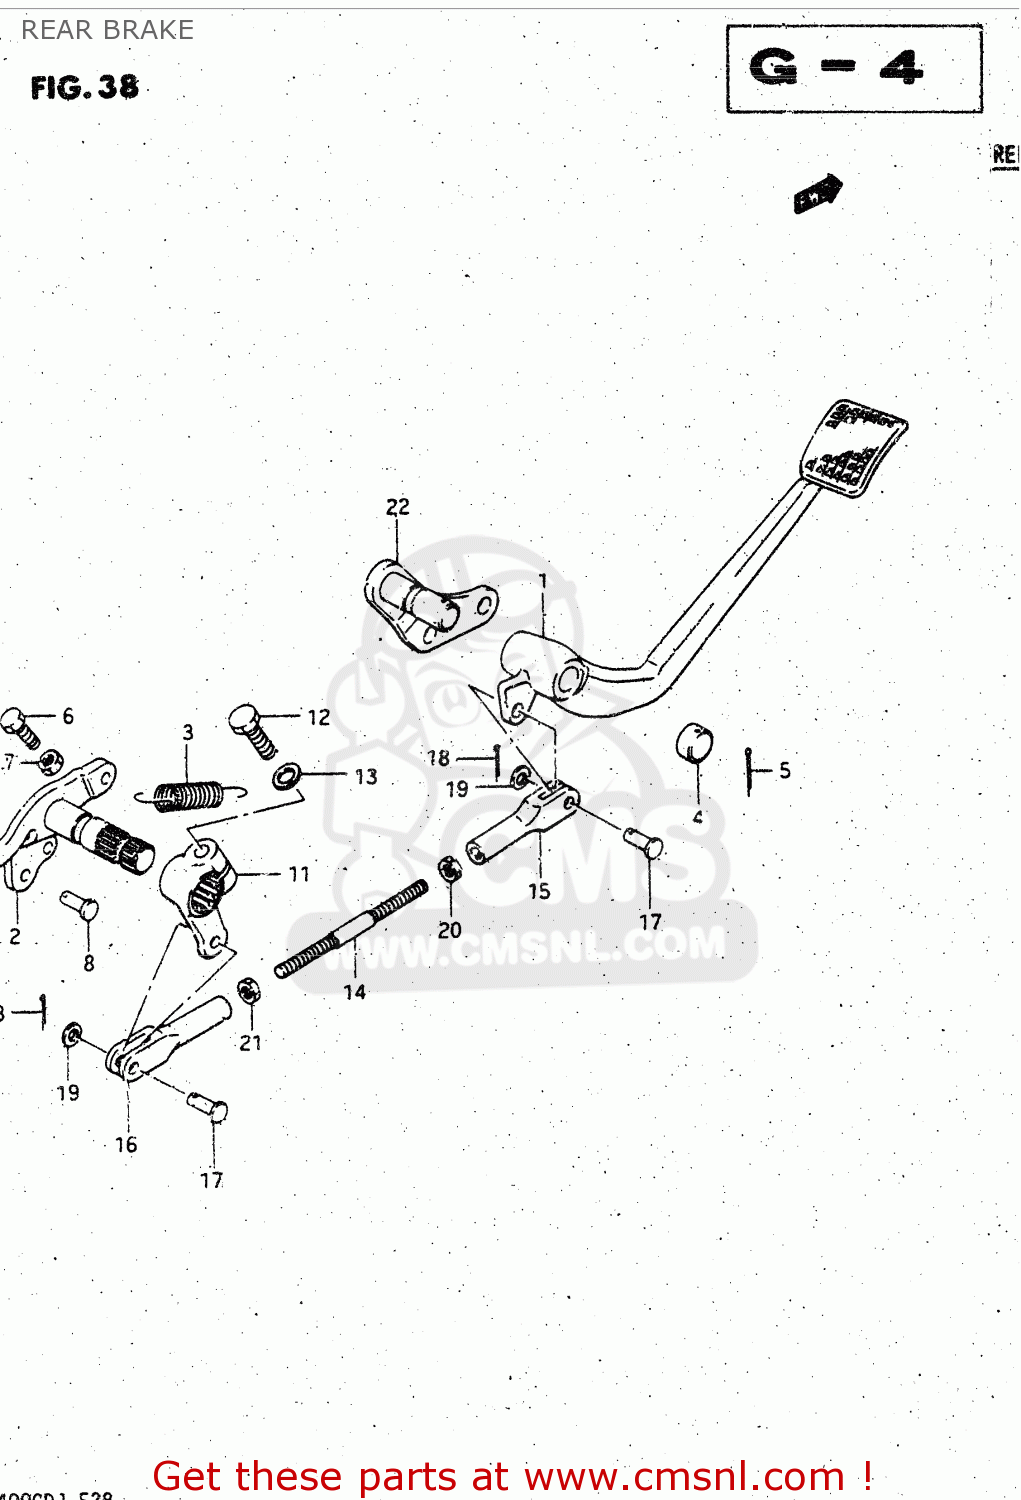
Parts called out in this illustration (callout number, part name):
1	PEDAL COMP,BRAKE
2	ARM,REAR MASTER CYLINDER
3	SPRING
4	CAP,BRAKE PEDAL
5	COTTER PIN
6	BOLT(6X23)
7	NUT 6MM
8	PIN
9	WASHER
10	PIN
11	ARM,BRAKE PEDAL LINK
12	BOLT
13	LOCK WASHER
14	LINK,BRAKE PEDAL
15	JOINT,BRAKE PEDAL,FRONT
16	JOINT,BRAKE PEDAL,REAR
17	PIN
18	PIN 20X20
19	WASHER
20	NUT
21	NUT 8MM
22	BAR,BRAKE PEDAL BOSS
